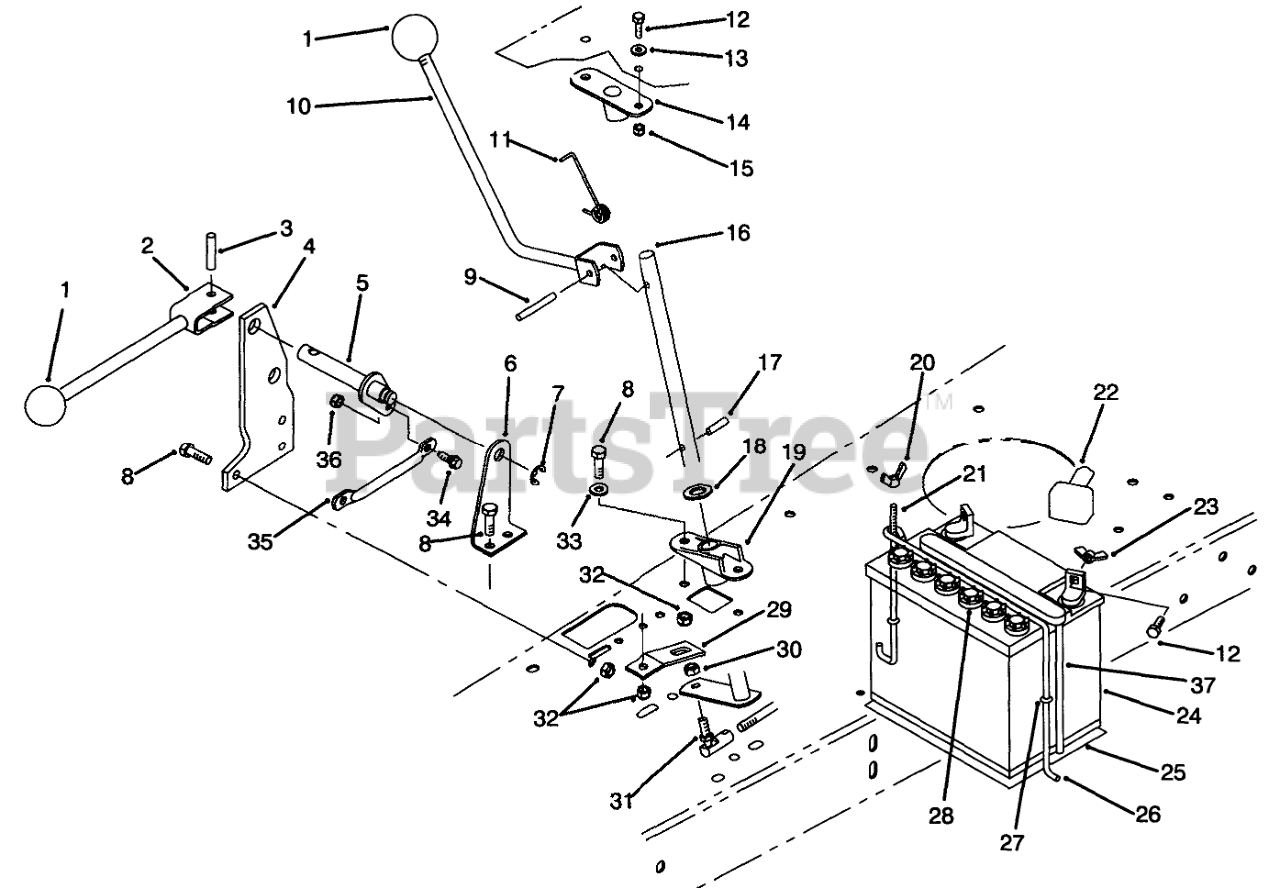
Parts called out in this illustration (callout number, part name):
2	Lever W.A.-Engage
3	PIN-ROLL
4	Pivot-Outer
5	PIVOT SHAFT WA
6	Bracket-Pivot, Inner
7	RING-RETAINING, EXTERNAL
8	SCREW-HH
9	PIN-ROLL
10	Lever W.A.-Shaft
11	SPRING-TORSION
12	SCREW-HH
13	WASHER-FLAT
14	SUPPORT-SHIFT SHAFT
15	NUT-LOCK, NI
16	SHAFT-SHIFT
17	PIN-SPRING
18	WASHER-THRUST
19	SUPPORT-LOWER SHIFTER
20	NUT-WING
21	POST-BATTERY
22	BOOT-TERMINAL
23	NUT-WING
24	Battery-12 Volt(Incl. Ref. #28 & 37)
25	PAD-SKID, ANTI
26	HOLDDOWN-BATTERY
27	O-RING
28	CAP-BATTERY
29	RETAINER-TRACTION SPRING
30	NUT-LOCK
31	JOINT-BALL
32	NUT-LOCK, NI
33	WASHER-PLAIN
34	SCREW-SHOULDER
35	LINK-BELLCRANK
36	NUT-HEX
37	TUBE-BATT DRAIN/80-2600
